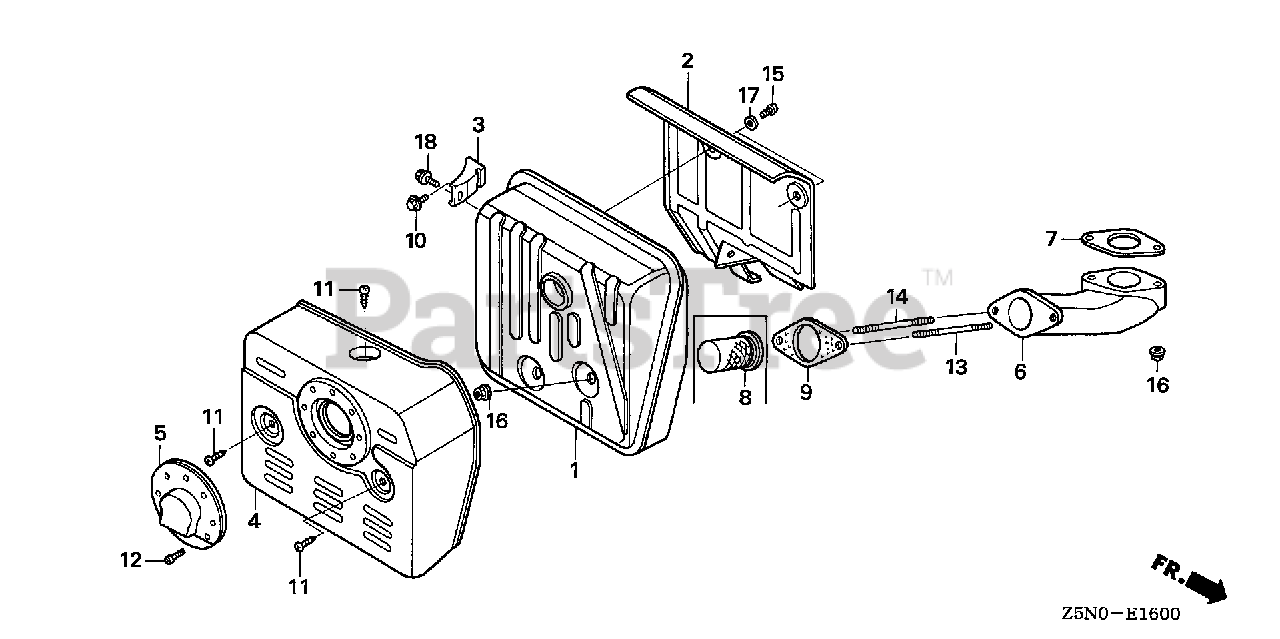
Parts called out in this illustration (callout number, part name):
1	MUFFLER
2	SEPARATOR, MUFFLER
3	STAY, MUFFLER
4	PROTECTOR, MUFFLER
5	CAP, MUFFLER
7	GASKET, EX. PIPE
9	GASKET, EX. PIPE
10	BOLT, FLANGE (8X16)
11	SCREW, TAPPING (5X8)
12	SCREW, TAPPING (4X6)
13	BOLT, STUD (8X60)
14	BOLT, STUD (8X70)
15	SCREW, PAN (6X6)
16	NUT, FLANGE (8MM)
17	WASHER, PLAIN (6MM)
18	BOLT, FLANGE (8X14)
